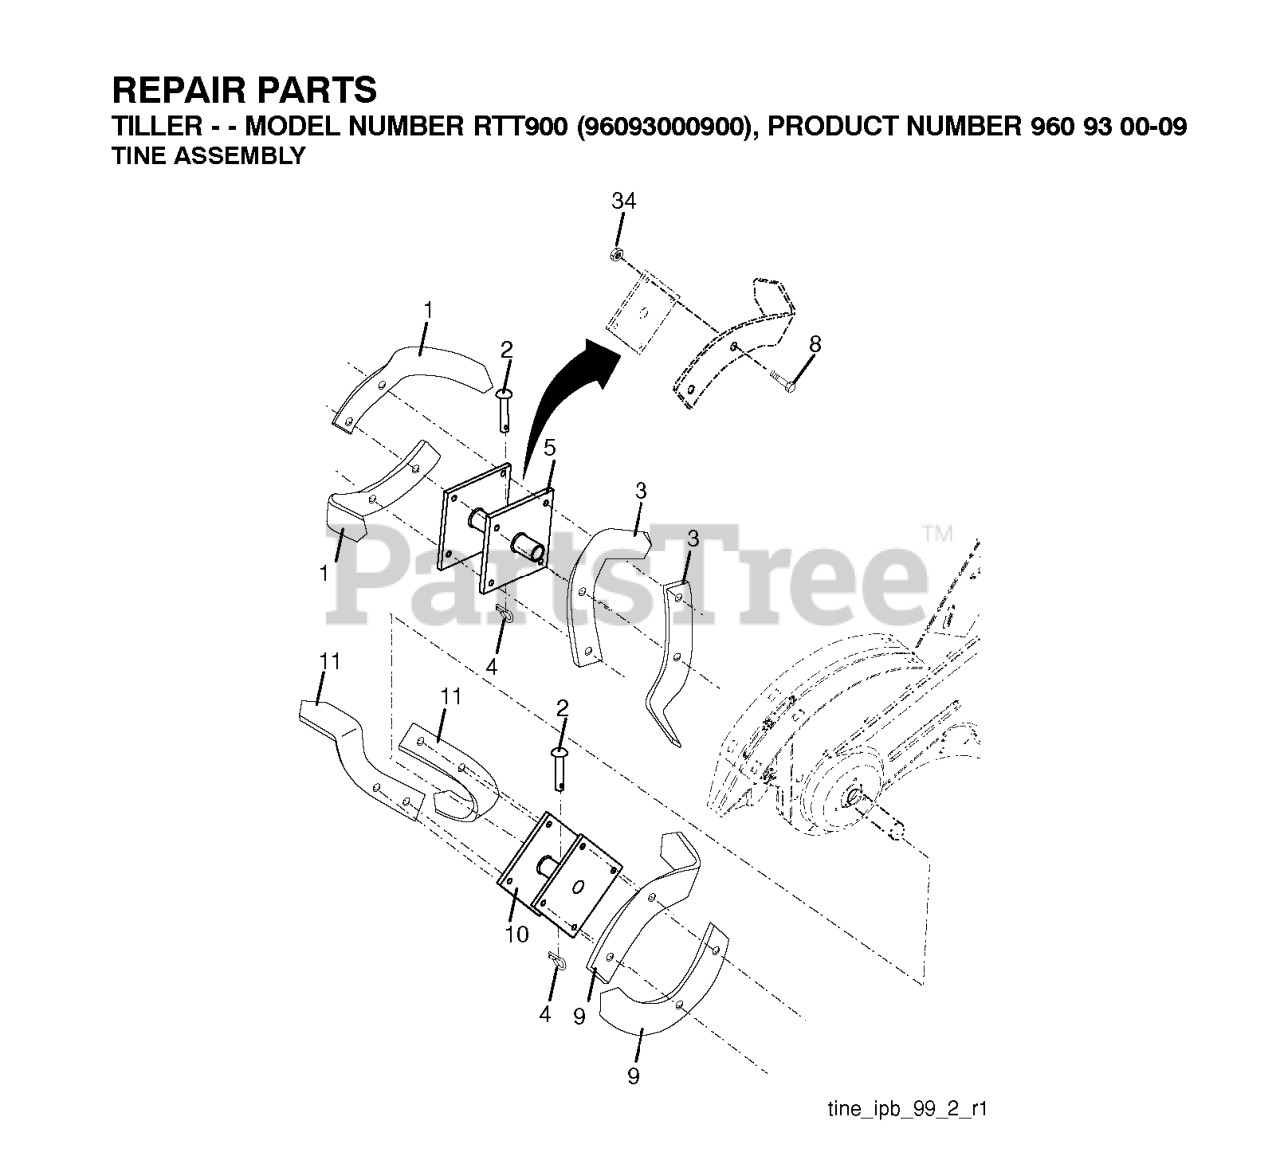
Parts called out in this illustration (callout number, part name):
1	TINE TI
2	PIN RETAINING SCREW
3	TINE.LH.12"(72L)
4	SPRING RETAINER
5	HUB.&.PLATE.LH.TILLER.BLACK
8	BOLT.HEX.001X20.37-24X1.ZINC
9	TINE TI
10	HUB.ASM.RH.14".BLACK.TILLER
11	TINE.RH.12"(72R)
34	NUT CROWNLOCK 3/8-24
